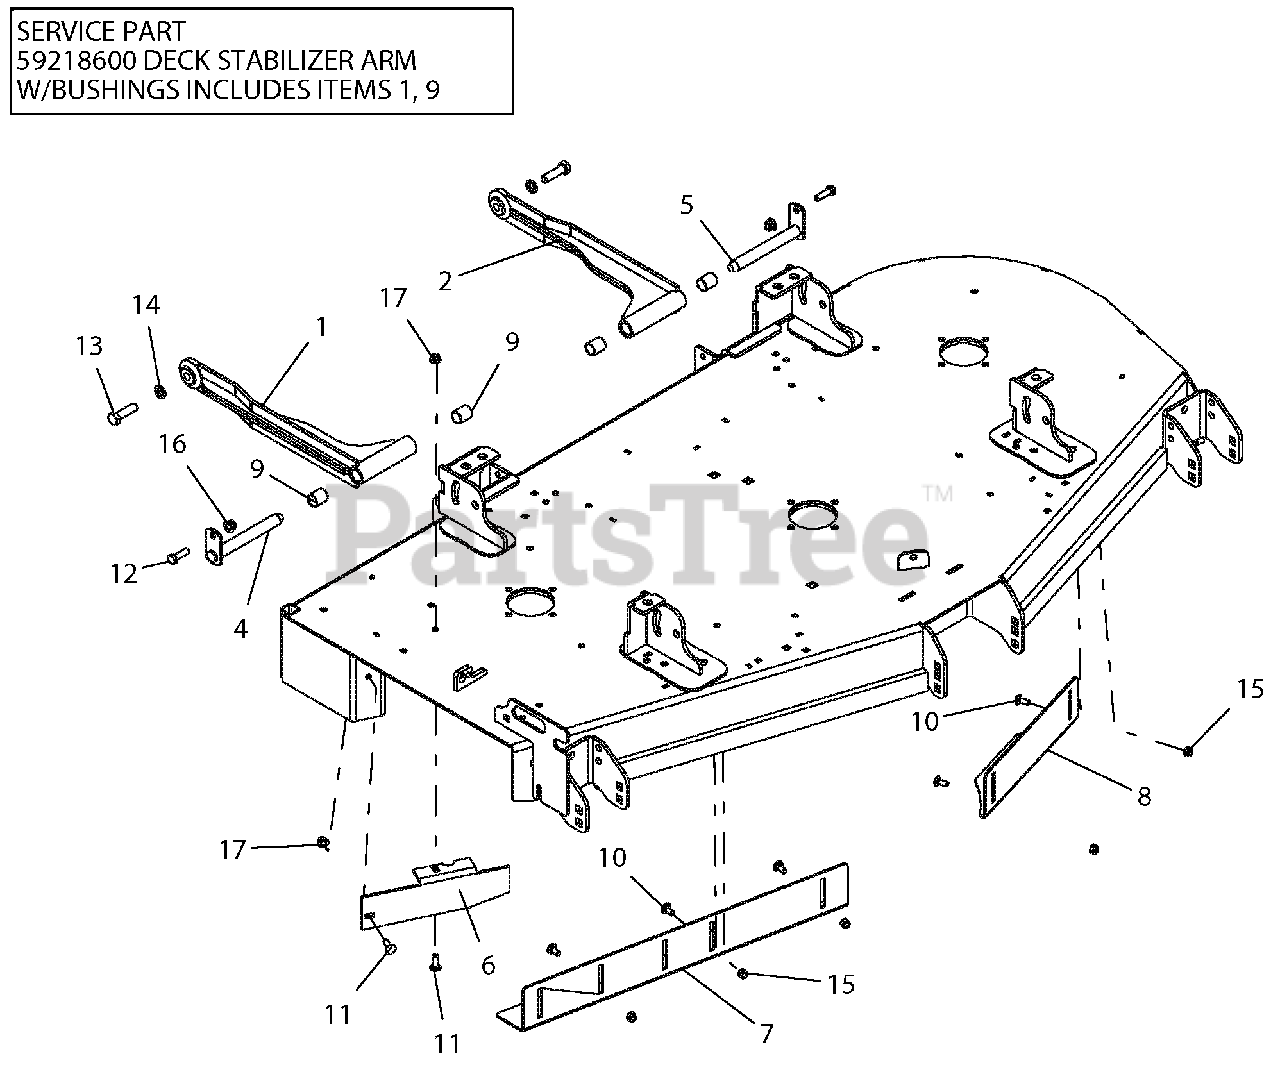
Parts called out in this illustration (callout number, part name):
1	WMT, DECK STABILIZER ARM-BLACK
2	WMT, DECK STABILIZER ARM-BLACK
4	WLDMT, MOWER MTG. PIN
5	WLDMT, MOWER MTG. PIN
6	BAFFLE, 60" DISCHARGE
7	BAFFLE, 60" RH VACUUM
8	BAFFLE, 60" LH VACUUM
9	BRG, .75 X .875 X 1.00
10	BLT-RDHDSQNK .31-18X.75 G5 YWZC
11	BLT-RDHDSQSHNK .31-18X1.00 G5 Y
12	BLT-HEX .38-16X1.25 GR5 YWZC
13	BLT-HEX .50-13X1.75 GR5 YWZC EP80
14	WSHR-LK .50X.125 REG YWZC
15	NUT-LK-NYL .312-18 YWZC
16	NUT-LK-NYL-FLG .38-16 YWZC
17	NUT-LK-NYL-FLG .31-18 YWZC
